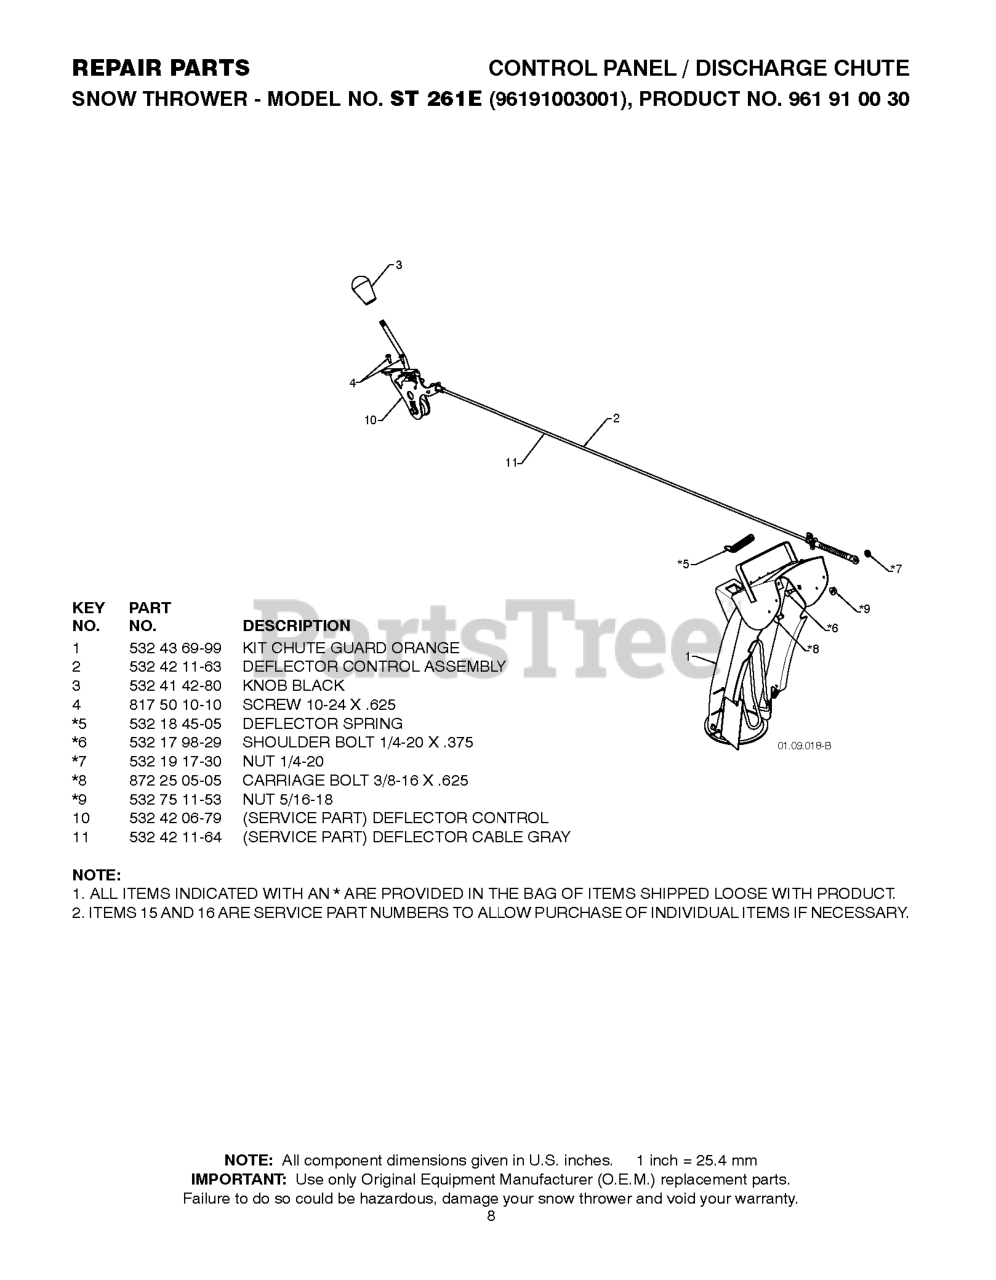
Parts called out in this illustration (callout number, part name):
2	CONTROL.ASM.DEFLECTOR
3	KNOB LEVER, BLACK
4	SCREW #10-24 X 5/8
10	RP CNTRL.HEAD.ASSEM.DEFLECTOR
11	SERVICE.CHUTE.DEF.CBL.GRY
